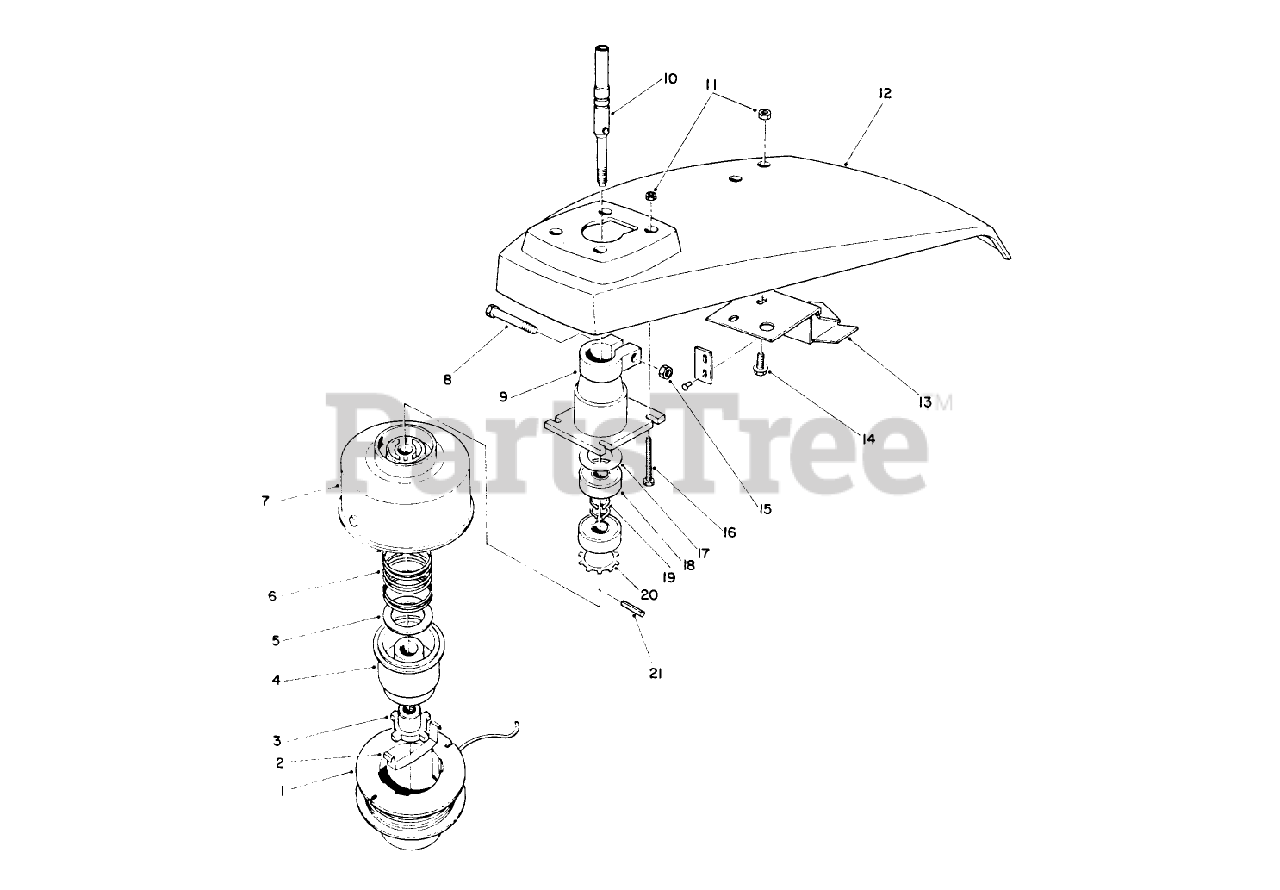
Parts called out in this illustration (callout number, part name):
3	DRIVER
4	SPOOL CORE
5	WASHER-FLAT
6	SPRING COMPRESSION
7	DRUM/EYELET
8	SCREW-HH
10	Shaft-Power
11	NUT-LOCK, NI
14	SCREW-HWH
15	NUT-LOCK, NI
16	SCREW-HH
17	Washer
18	Ball Bearing
19	Snap Ring
20	Grip-Spring
